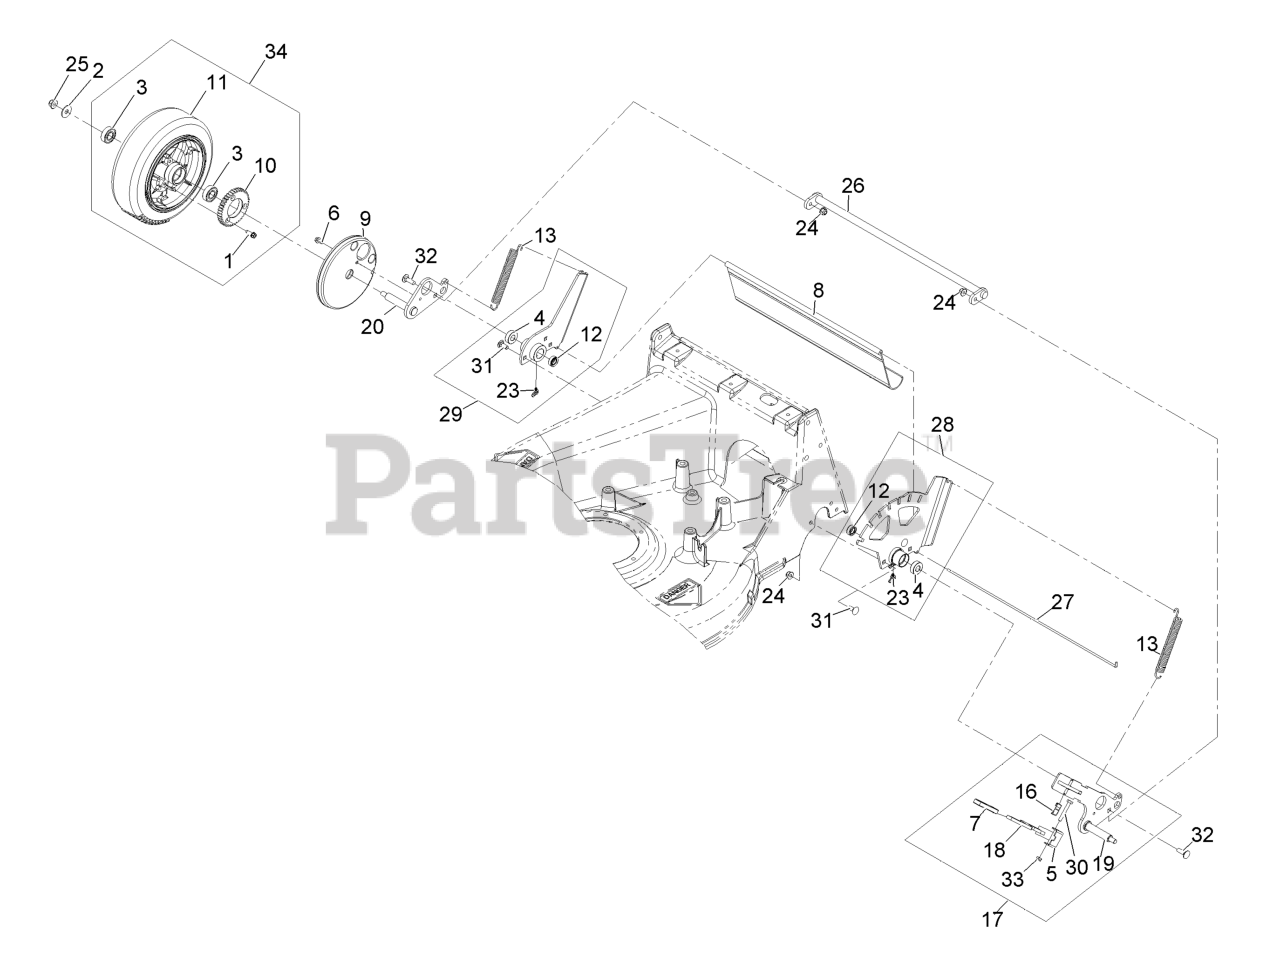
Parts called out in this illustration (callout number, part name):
1	SCREW-TORX
3	BEARING-BALL
4	BEARING-AXLE, REAR
5	BRACKET-PIVOT, LIFT
7	COVER-HANDLE
8	SHIELD-REAR
9	COVER-GEAR
10	GEAR-DRIVEN
11	ASM,10" TIRE AND WHEEL
12	SEAL-AXLE
13	SPRING-ASSIST, LIFT
16	SPRING-LATCH
17	ASM,REAR ADJUSTER
18	LEVER-LIFT
19	ARM-AXLE, LH
20	ARM-AXLE, RH
23	FITTING-GREASE
24	NUT-HF, NI
25	NUT-HF, NI
26	ROD-TORQUE
27	ROD-SHIELD
28	LH BEARING SUPPORT ASM
29	RH BEARING SUPPORT ASM
30	SCREW-HH
31	BOLT-CARR
32	BOLT-CARR
33	NUT-LOCK, NI
34	10 INCH WHEEL ASM
